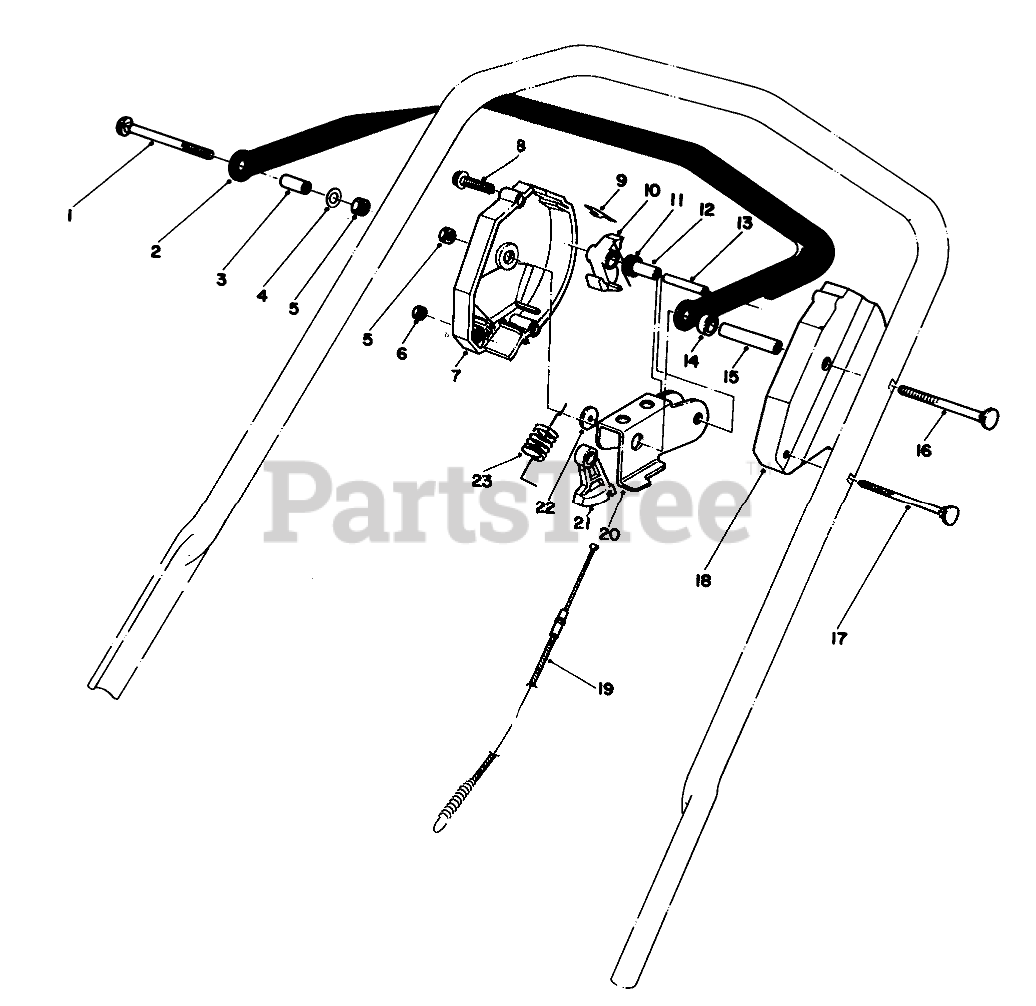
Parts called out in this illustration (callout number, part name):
1	5/16-18 X 2 HNDLE SCREW
2	Bar-Control
3	Spacer
4	WASHER-FLAT
5	NUT-LOCK, NI
6	NUT-LOCK, NI
7	Housing Control R.H.
8	SCREW-HWHTF
9	LEAF SPRING
10	Clamp-Cable
11	SPRING-TORSION
12	SPACER
13	PIN-ROLL, SLOTTED
14	SPACER-NYLON
15	TUBING-SPACER
16	5/16-18 X 3 HNDLE SCREW
17	HANDLE SCREW
18	HOUSING-CONTROL, LH
19	Cable-Clutch
20	Rocker
21	LEVER-CABLE
22	PLASTIC WASHER
23	Spring-Extension
